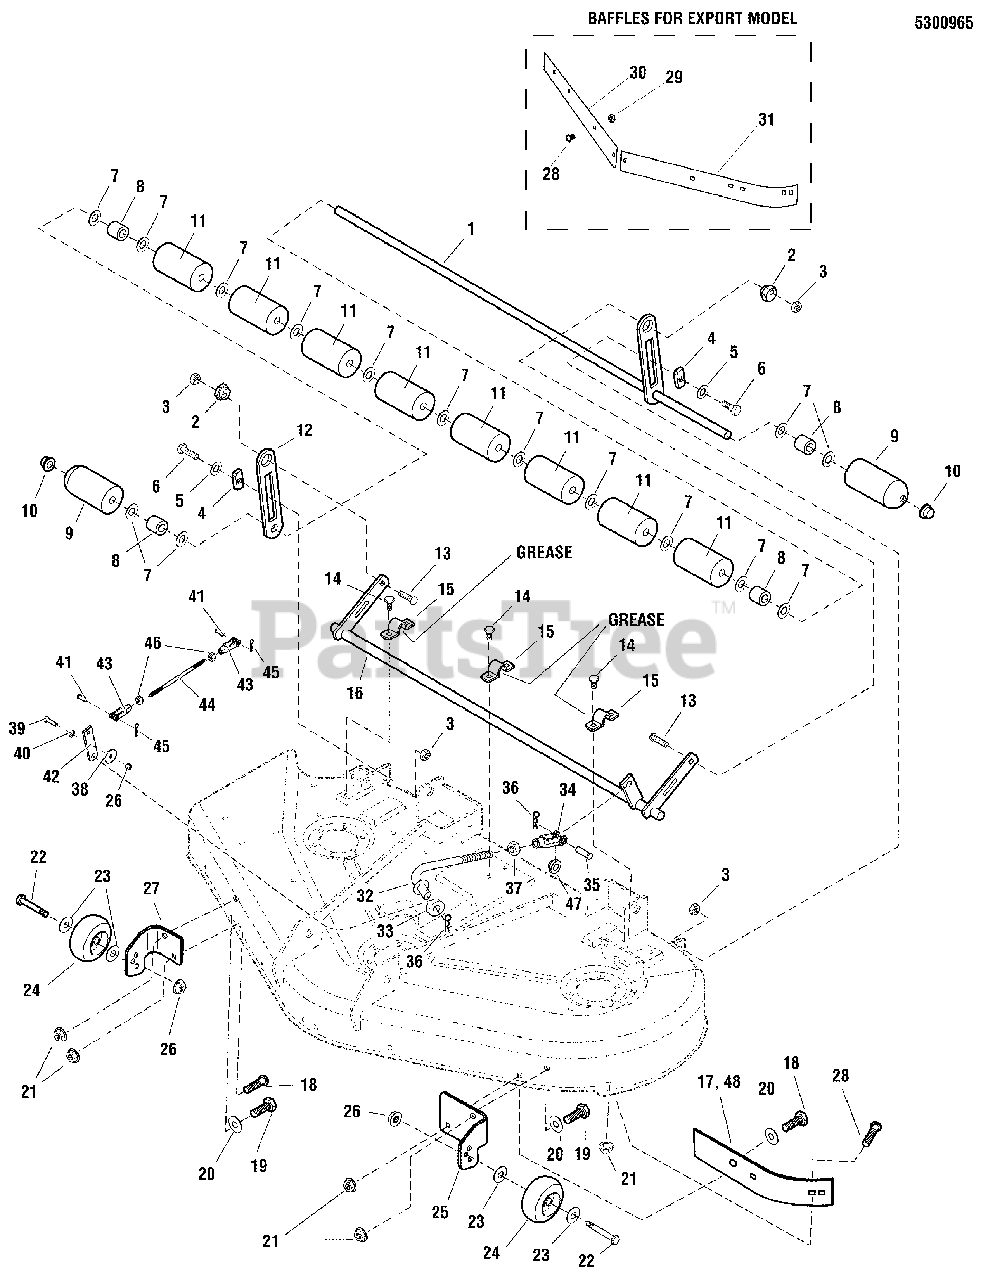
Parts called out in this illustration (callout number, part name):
1	WELD,SHAFT,ROLLER,50
2	NUT, Hex Adjusting, .99 DIA .687
3	NUT-HEX TOPLOCK SPIRAL FLNG 3/8-16 YEL
4	SLIDE .803 X 1.7
5	WASHER-0500(0.53IDX1.25X.08THK)BLK
6	BOLT, Shoulder, 3/8-16 X 1.34
7	WASHER, 5/8
8	SPACER, .876 OD X .666 ID X 1.25 LG
9	ROLLER-0.650ID 2.50OD ROUNDED BLACK POLY
10	NUT-PUSH FOR .625 DIA STUD CAPPED BLK
11	ROLLER-0.652ID 2.50 OD 4.10LG BLACK POLY
12	BAR, ROLLER
13	BOLT-RD HD SH SQ NK 3/8-16X1.500 G5 BLK
14	SCREW-HEX WSHR HD TAPTT5/16-18X0.750BLK
15	STRAP-1.00WD 3.06LG .134THK ROLLER ECOAT
16	WELD, SHAFT, DECK LIFT, 50" ORANGE
17	SHORT BLOWOUT BAFFLE BLACK
18	BOLT, 5/16-18 X 1, CARRIAGE
19	CAPSCREW, HEX HEAD,5/16-18 X 1
20	WASHER, 5/16 SAE
21	NUT, 5/16-18 HEX NYLOCK FLANGE
22	BOLT-WHEEL 3/8-16X2.781 .750 THRD YELLOW
23	WASHER-0500(0.51IDX0.87ODX.06THK) BLK
24	WHEEL- 2.00 WIDE 3.92 DIA 0.531ID POLY
25	BRACKET, GAUGE WHEEL, LH
26	NUT, 3/8-16 HEX NYLOCK FLANGE
27	BRACKET, GAUGE WHEEL, RH
28	BOLT, 5/16-18 X 3/4", CARRIAGE
29	NUT, 5/16 - 18 HEX NYLON LOCK
30	BLOWOUT BAFFLE, RH 50" MOWER - BLACK
31	BLOWOUT BAFFLE, LH 50" MOWER - BLACK
32	ROD, DECK LIFT LINKAGE
33	BUSHING, REAR QUICK TACH, CZ
34	CLEVIS, 1/2-20, STEEL
35	PIN, CLEVIS, 1/2 X 1 1/2, YZP
36	PIN, HAIR, .0915 X 1-7/8
37	NUT, 1/2-20 HEX JAM
38	WASHER, .41 X 1.75 X .14
39	BOLT, 3/8-16 X 1-1/2 GD5 YZ
40	WASHER, 3/8 SAE
41	PIN, CLEVIS, 3/8 X 1
42	LINK, ROLLER REVERSE
43	CLEVIS 3/8-24, PLASTIC
44	ROD, LEVER CONNECTING
45	PIN, COTTER, 3/32" X 3/4
46	NUT, 3/8-24 HEX JAM
47	BUSHING, DECK SUPPORT
48	BAFFLE FRONT 44, 50 MOWERS
